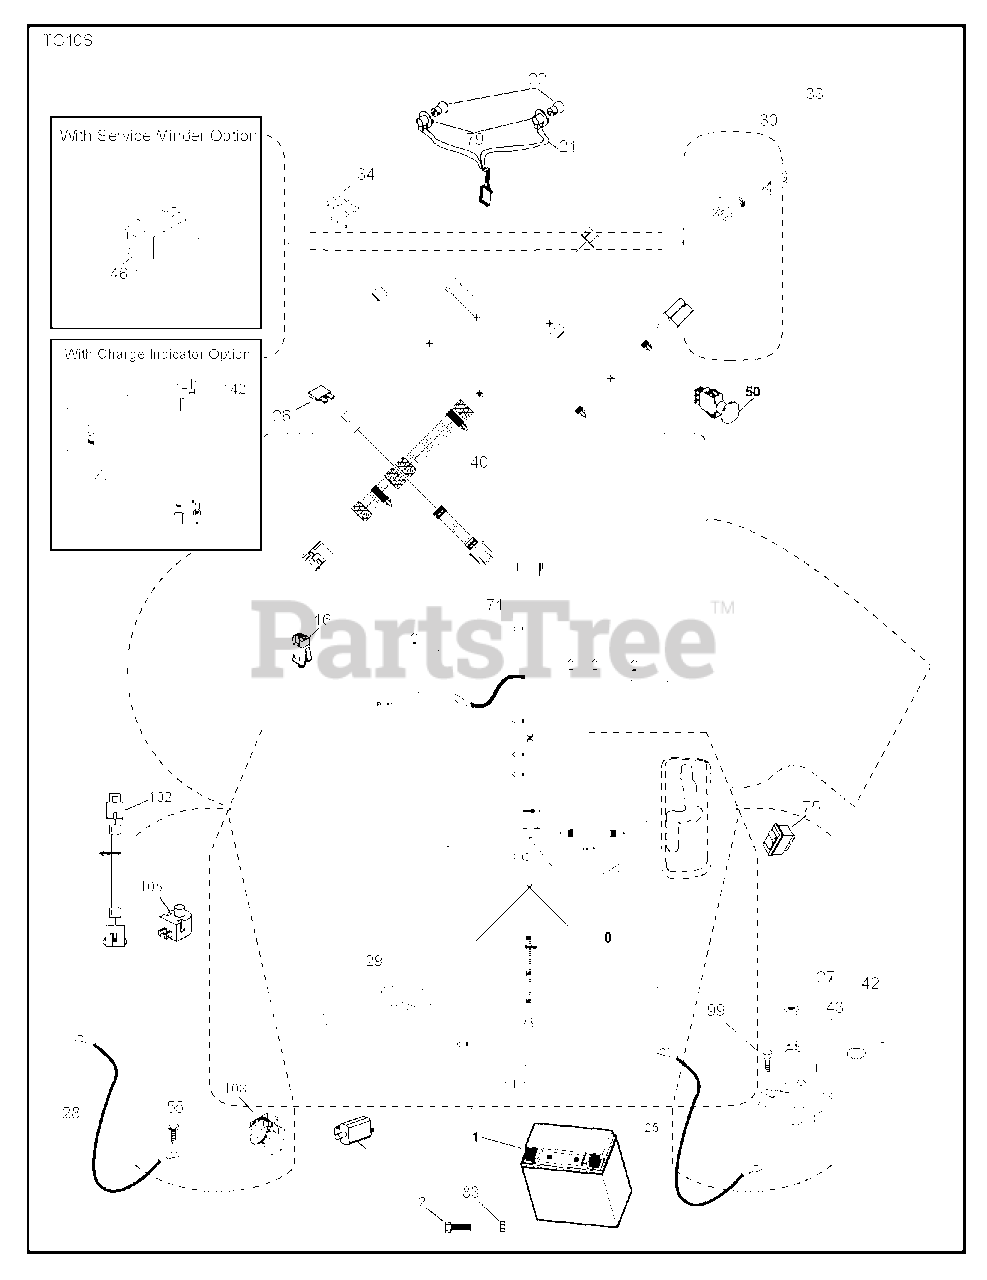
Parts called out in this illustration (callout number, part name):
1	BATTERY BATTERY 14AH 12V LEOC
2	SCREW.HEX.HEAD.CAP.M6 X1.12W
16	SWITCH INTERLOOK PUSH-IN
21	HARNESS.LIGHT W/4152J BULBS
25	CABLE BATTERY CABLE
26	FUSE 20AMP
27	NUT
29	SWITCH.SEAT.DELTA.OPC.
30	SWITCH.IGN.DELTA.W.LGH.ROS
33	KEY.CHAIN.BLISTER.PACK.GEN.INT
40	RP HARNESS.ELECTRICAL.DASH.SRD
42	TERMINAL COVER
43	SOLENOID.W/BRASS.PLUNGER
46	RP GUAGE.SRVCMNDR.HRMTR.
55	SCREW 5/16"
71	HARNESS-CHASSIS SUB
75	SWITCH.BAG.DUMP
79	BULB HOLDER ASM.
83	NUT NUT SQUARE
99	SCREW
102	HARNESS PIGTAIL PCH TEX ROS
105	REVERSE SWITCH
107	.WITCH.FULL BAGGER.INDICATOR
108	SWITCH.SNAPMOUNT.NC
142	RP HARNESS.JUMPER.CTEK
